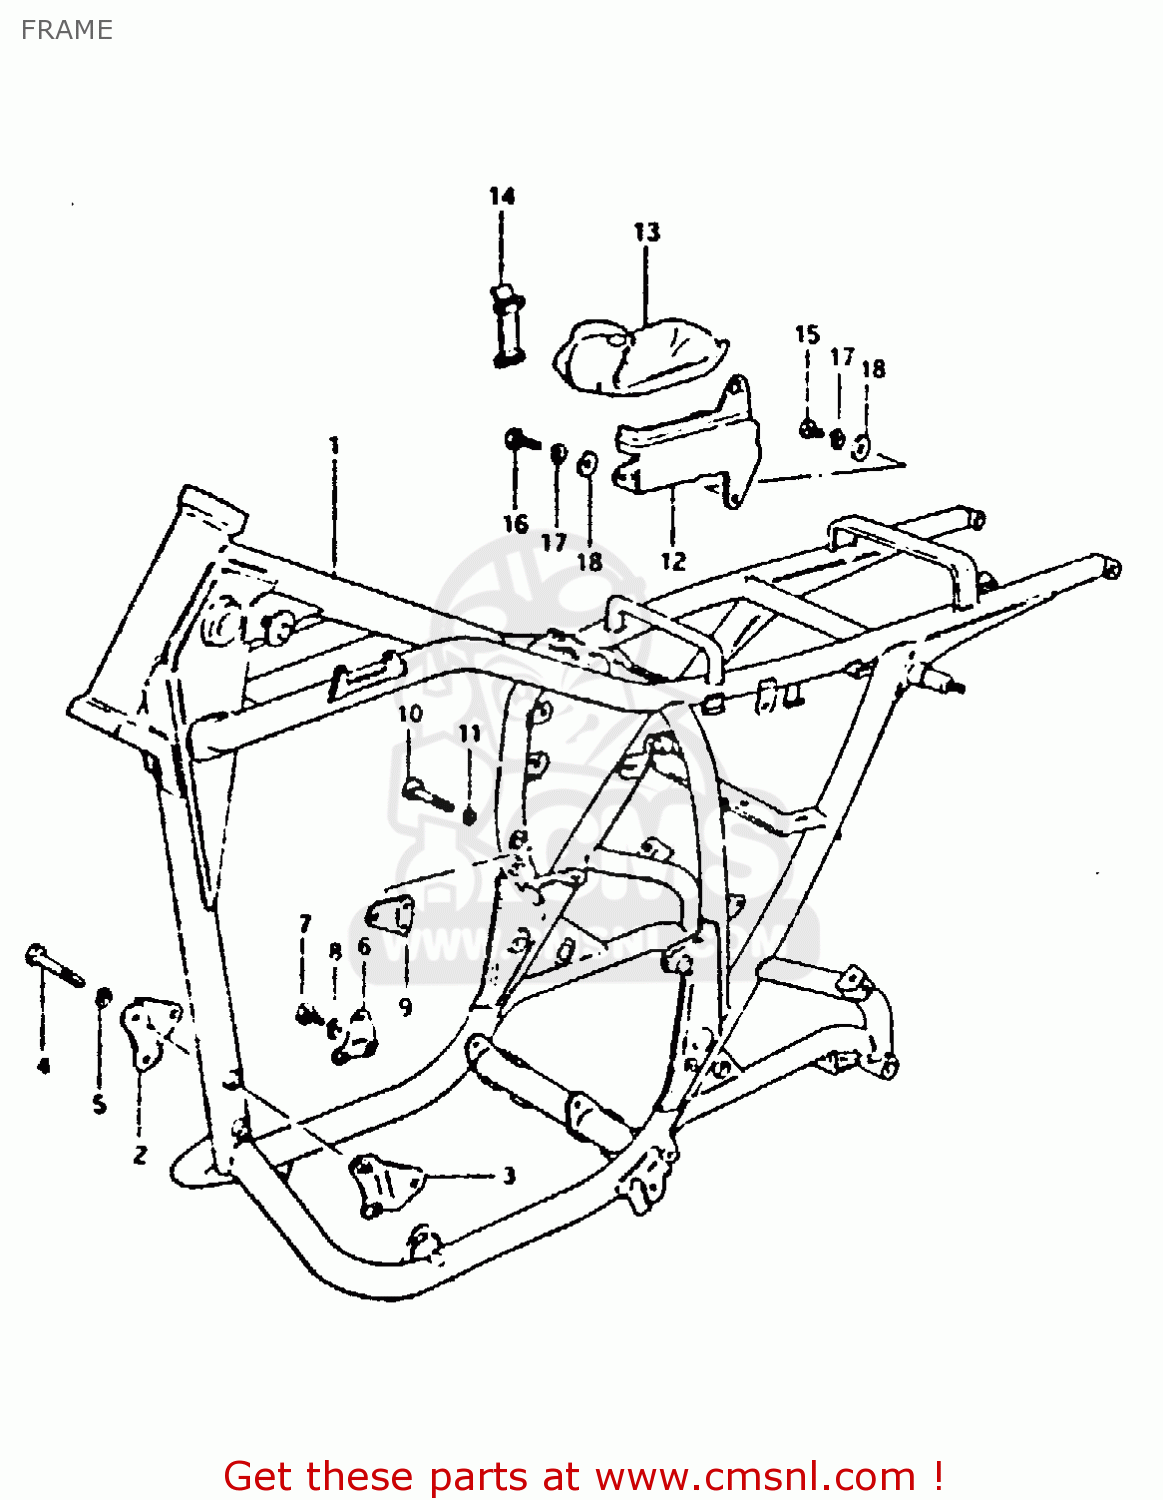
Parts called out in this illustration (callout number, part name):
1	FRAME
2	PLATE,ENGINE MOUNTING
3	PLATE,ENGINE MOUNTING
4	BOLT
5	LOCK WASHER
6	PLATE,ENGINE MOUNTING
7	BOLT
8	LOCK WASHER
9	PLATE,ENGINE MOUNTING
10	BOLT 8X45
11	LOCK WASHER
12	HOLDER,TOOL
13	TOOL ASSY
14	BAND
15	SCREW 6X12
16	SCREW
17	LOCK WASHER
18	WASHER
